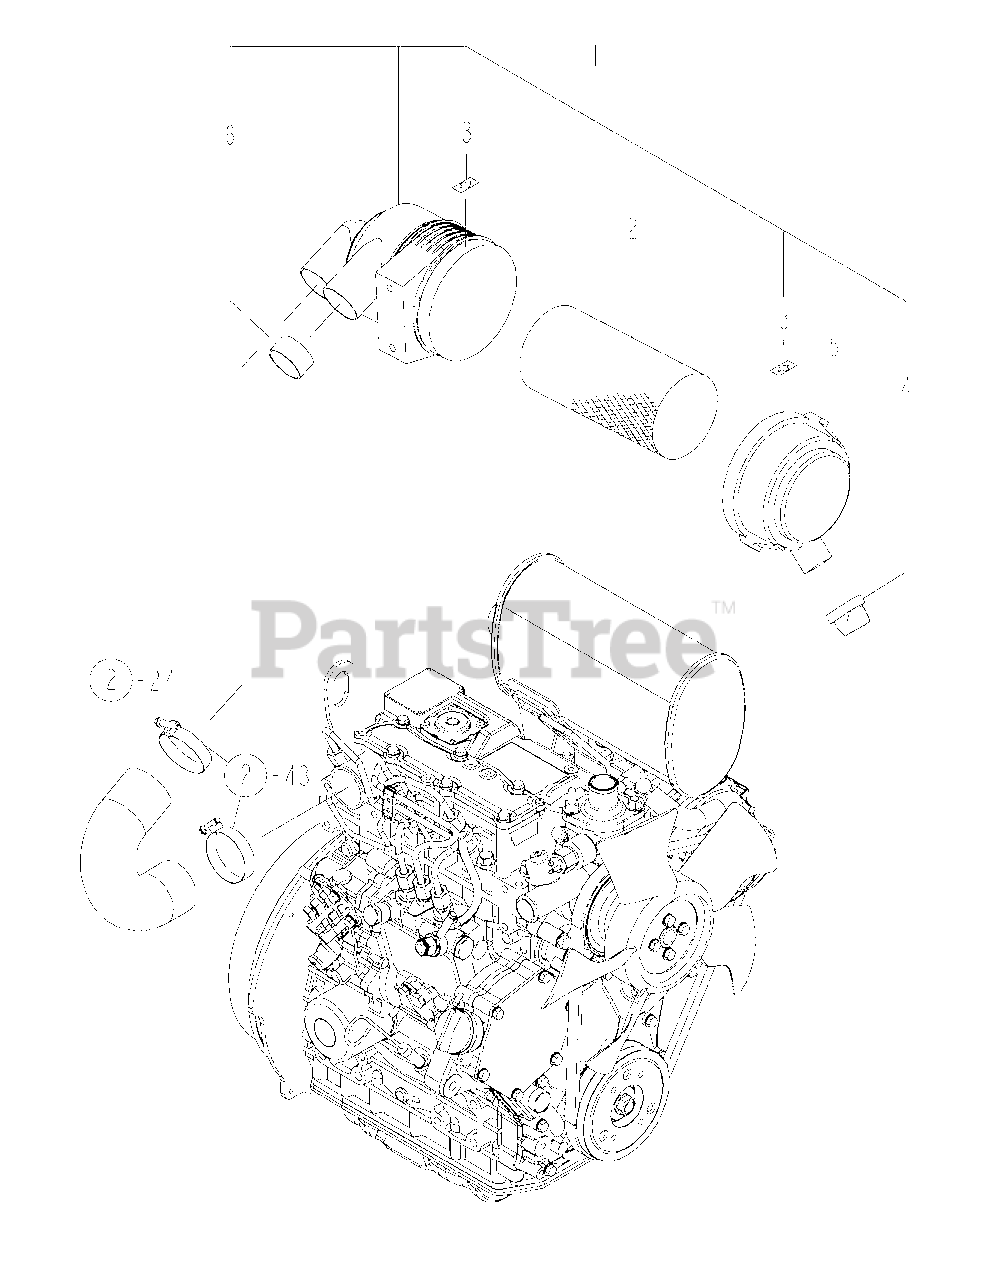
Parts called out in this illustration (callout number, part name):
1	CLEANER ASSY, AIR
2	ELEMENT 4, CLEANER
4	VALVE, UNLOADER
